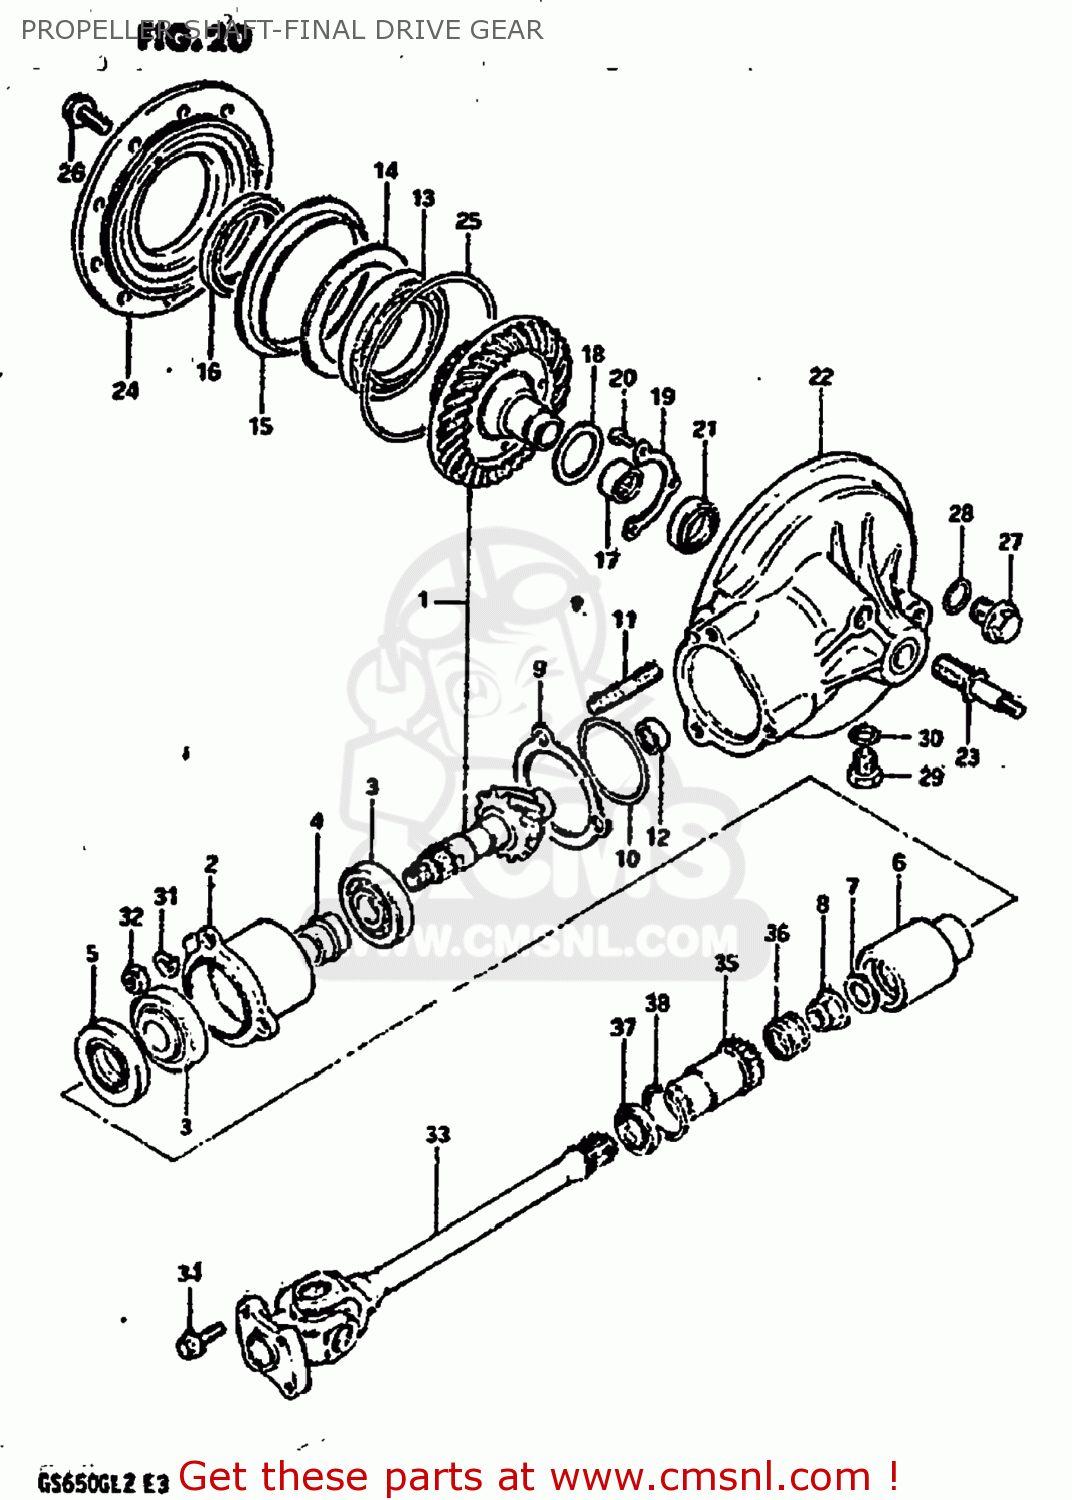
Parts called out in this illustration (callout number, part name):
1	GEAR SET,FINAL BEVEL (N
2	HOUSING,DRIVE GEAR
3	BEARING
4	SPACER
5	SEAL,OIL(32X54X7)
6	GEAR,FINAL DRIVE
7	WASHER(14X29X4)
8	NUT
9	SHIM,DRIVE GEAR HOUSING
10	O RING(D:2.4,ID:62.6)
11	STUD
12	BEARING(15X23X20)
13	BEARING(70X110X13)
14	SHIM,DRIVEN GEAR BEARING T0.35
15	PLATE,FINAL DRIVEN BRG OIL
16	SEAL,OIL(70X96X16)
17	BEARING(32X46X17.7)
18	SHIM,FINAL DRIVEN GEAR
19	RETAINER,FINAL DRIVEN GEAR BRG
20	SCREW 6X12
21	SEAL,OIL(30X42X7)
22	CASE,FINAL GEAR
23	STUD
24	CASE,FINAL GEAR BEARING
25	O RING(D:3.5,ID:131.6)
26	BOLT
27	PLUG
28	O-RING
29	PLUG
30	GASKET(14X19.2X2) (NAS)
31	WASHER,LOCK
32	NUT
33	SHAFT ASSEMBLY,PROPELLER
34	BOLT(8X17)
35	COUPLING,PROPELLER SHAFT
36	SPRING
37	SEAL,OIL(30X40.5X5.5)
38	CIRCLIP
